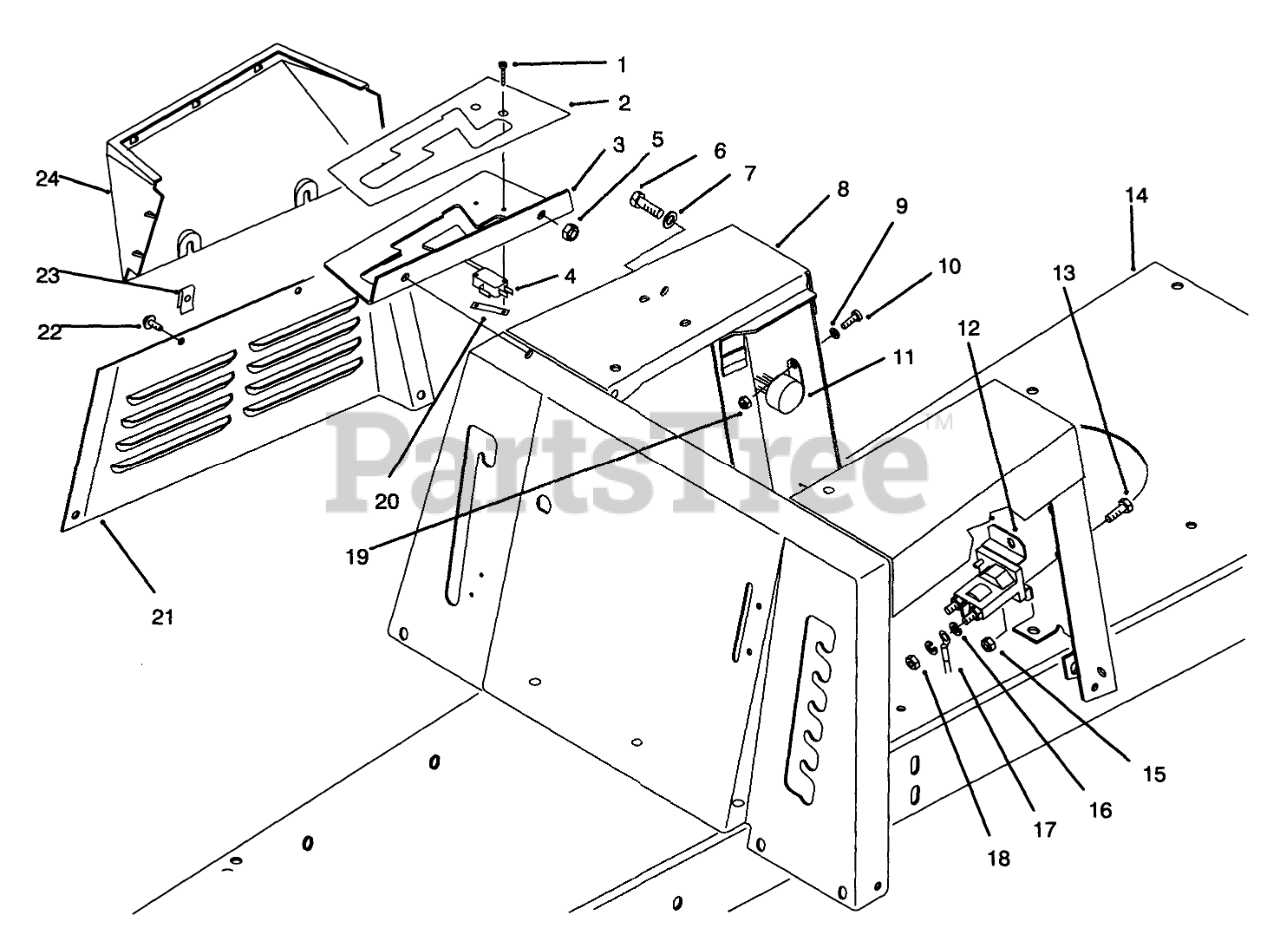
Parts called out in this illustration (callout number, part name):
1	SCREW-HH
2	DECAL - SHIFT PATTERN
3	Gate-Shift
4	SWITCH-MICRO
5	NUT-LOCK, NI
6	SCREW-HH
7	WASHER-PLAIN
8	Body W.A.-Seat Support
9	WASHER-FLAT
11	Relay
12	SOLENOID
13	SCREW-HH
14	Frame
15	NUT-LOCK, NI
16	WASHER-LOCK
17	WIRE ASM
18	NUT-JAM
19	NUT-LOCK, NI
20	NUT-SPEED
21	Panel-Seat Base, R.H.
22	SCREW-HWH
23	NUT-CLIP,U
24	COVER-SHIFT GATE
